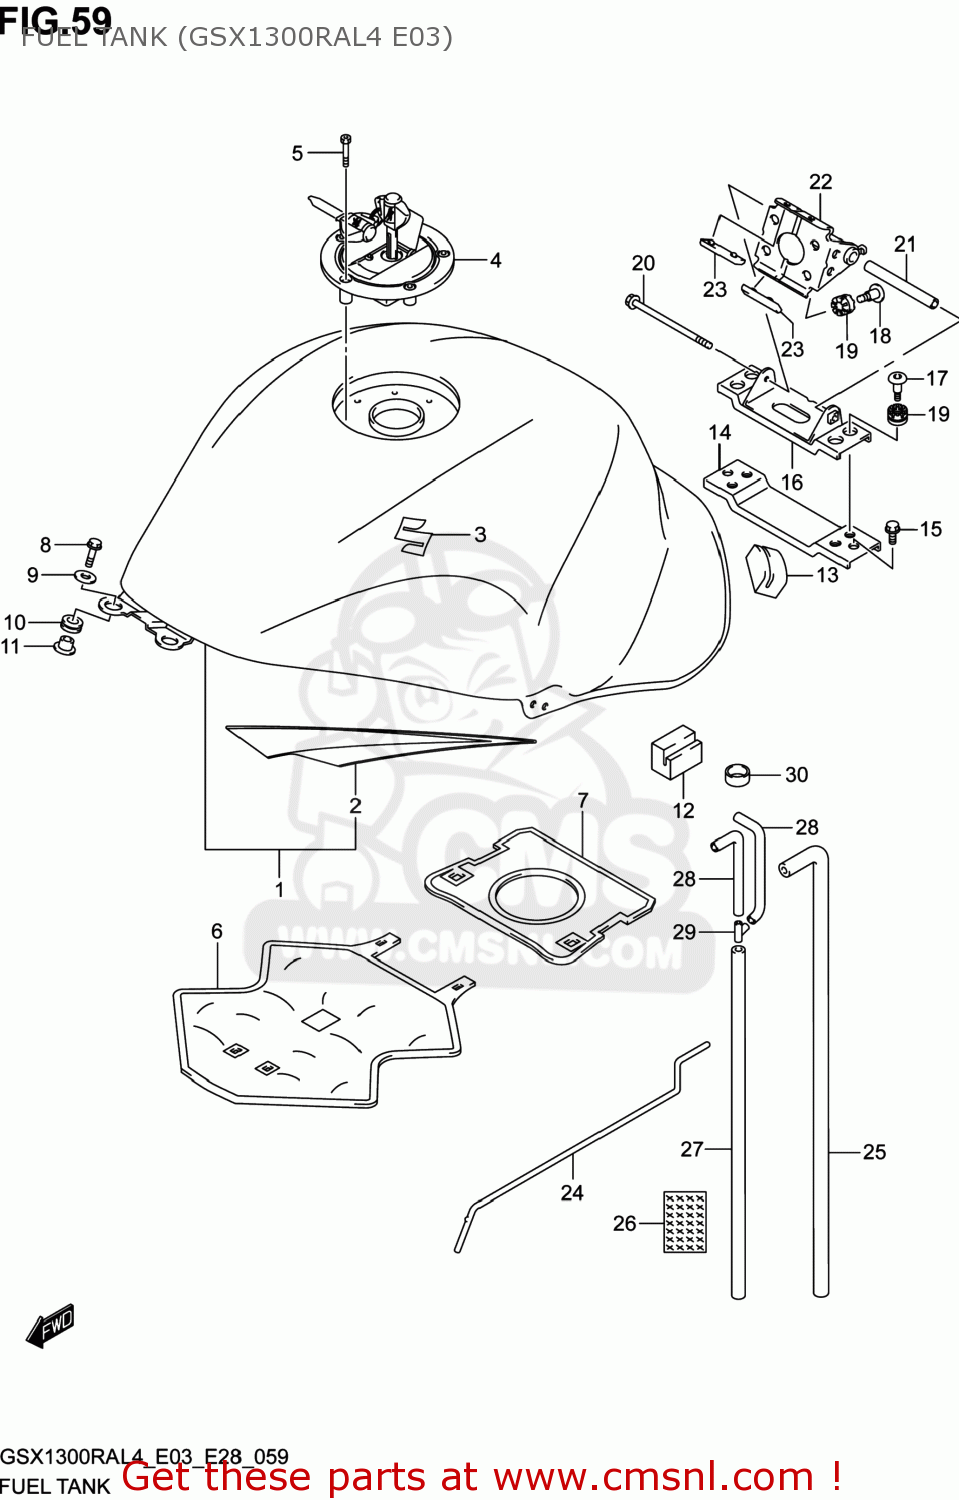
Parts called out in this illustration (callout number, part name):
1	TANK ASSY,FUEL(RED)
2	TAPE SET,FUEL TANK
3	EMBLEM, S
4	CAP SET,FUEL TANK
5	BOLT(5X20)
6	SHIELD,FUEL TANK HEAT NO.1
7	SHIELD,FUEL TANK HEAT NO.2
8	SCREW(6X25)
9	WASHER(6,5X22X1.6)
10	CUSHION,FUEL TANK FR
11	SPACER,FUEL TANK FR
12	CUSHION,FUEL TANK SIDE
13	CUSHION,FUEL TANK RR
14	BRACKET,FUEL TANK RR NO.3
15	BOLT
16	BRACKET,FUEL TANK RR NO.2
17	SCREW(6X22)
18	SCREW(6X22)
19	CUSHION
20	BOLT
21	SPACER,FUEL TANK RR
22	BRACKET,FUEL TANK RR NO.1
23	CUSHION,SEAT FR
24	STAY,FUEL TANK
25	HOSE,FUEL TANK DRAIN
26	SHIELD,DRAIN HOSE HEAT
27	HOSE,FUEL TANK BREATHER
28	HOSE,TANK BREATHER NO.2
29	3 WAY
30	HOSE(12X16X600)
